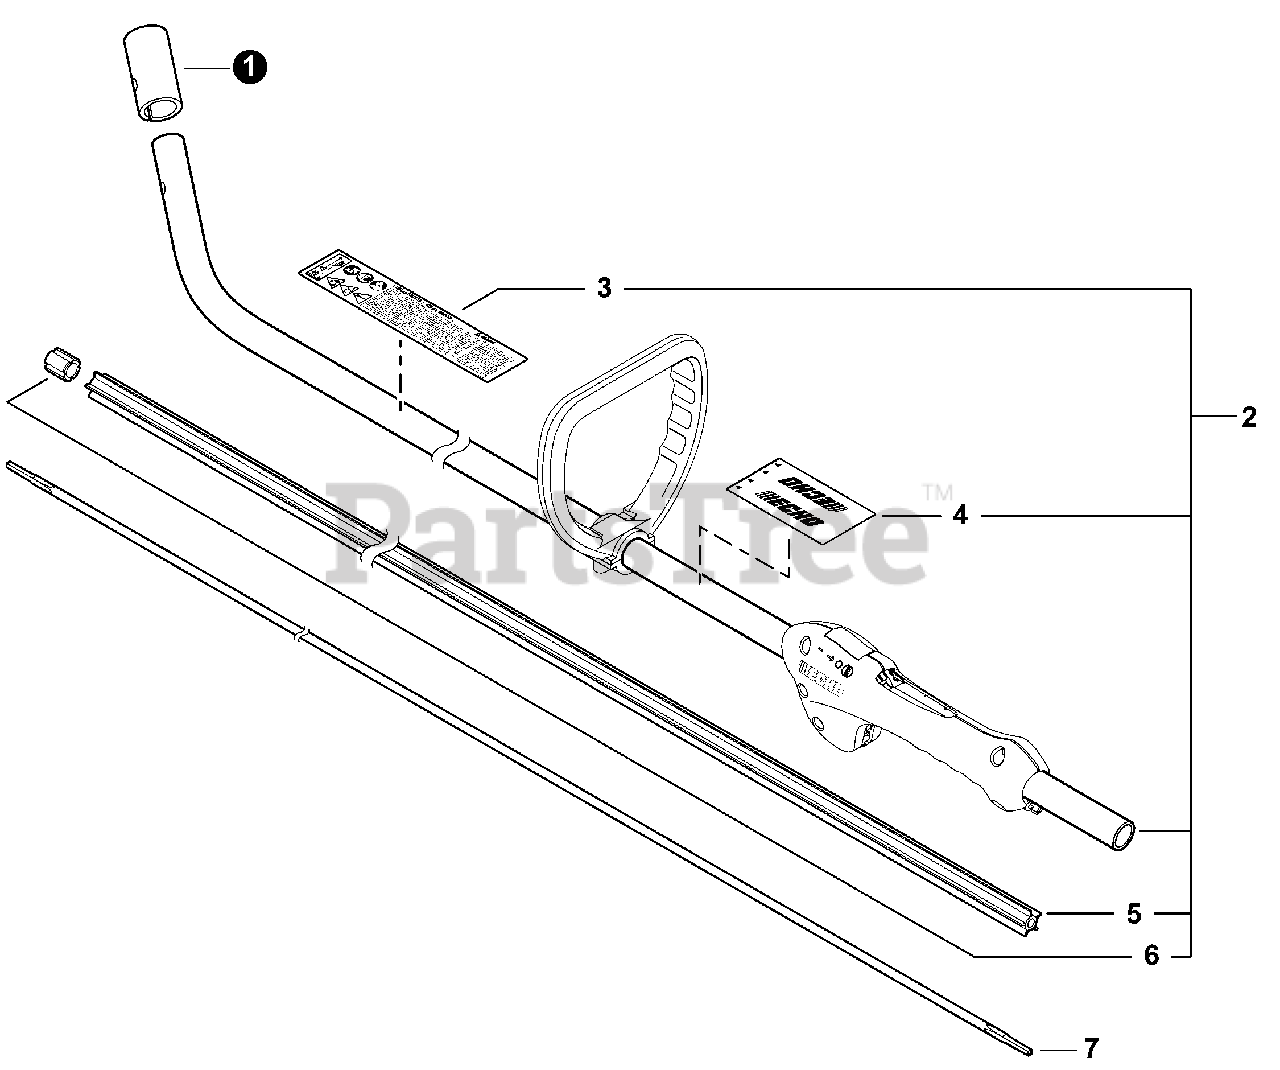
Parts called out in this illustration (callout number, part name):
2	MAIN PIPE ASSY
3	LABEL, CAUTION
4	LABEL, HANDLE LOCATION
5	LINER - FLEXIBLE
7	DRIVESHAFT - FLEXIBLE
